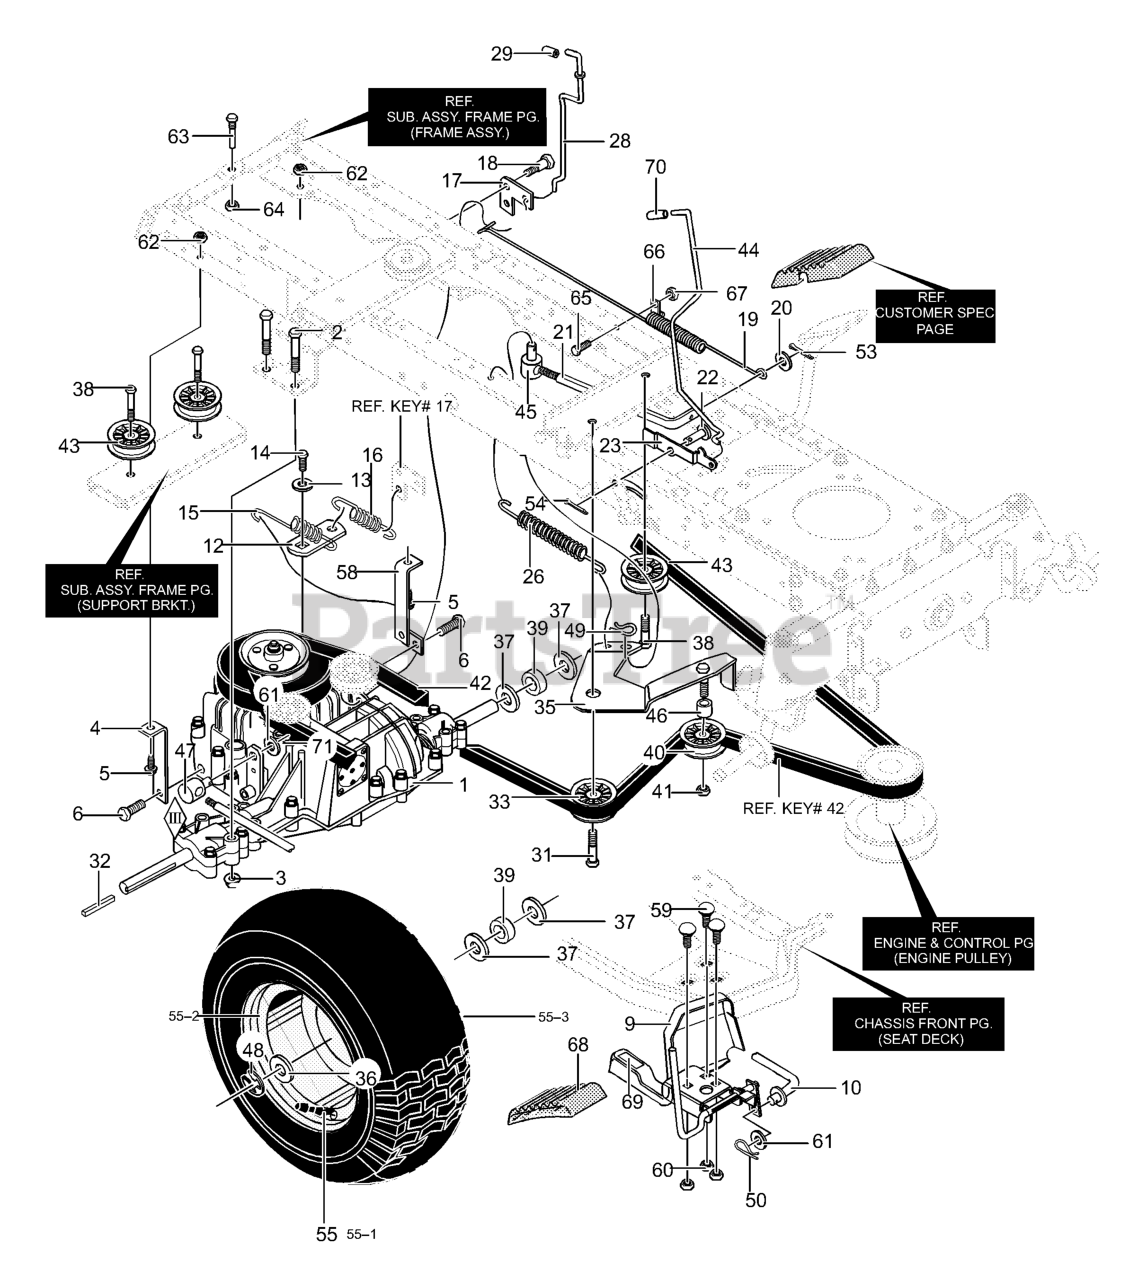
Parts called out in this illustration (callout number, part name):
1	Transaxle, VST205 **
2	Screw, 5/16-18 x 2.50
3	Nut, 5/16-18
4	Bracket, Stabilizer Hydro
5	Screw, 5/16-18 x 1.00
6	Screw, 5/16-18 x 0.75
9	Pedal Assy. Hydro
10	Rod, Foot Control
12	Bracket, Shift
13	Washer, Transaxle
14	Screw, 1/4-28x.750
15	Spring - Transaxle Disconnect
17	Bracket, Disconnect Lever
18	Bolt, HHSH 5/16-18
19	Spring, Brake
20	Washer, Flat
21	Rod, Clutch
22	Pin, Clevis
23	Latch, Park Brake
26	Spring, Tension
28	Rod, Disconnect
29	Grip, Hydro Disconnect
31	Screw, 3/8-16 x 1.25
32	Key, Square
33	Pulley, Idler
35	Assy, Idler Arm Traction
36	Washer, Flat
37	Washer, Flat
38	Screw, 3/8-16 x 1.25
40	Pulley, Idler
41	Nut, 3/8-16
42	Belt, V 4L 112.75
43	Pulley, Idler
44	Park Brake Rod
45	Nut, 5/16-18 Adjusting
47	Adjust Nut 1/2-13
48	E-Ring
49	Pin, Hair
50	Pin, Hair
53	Pin, Cotter
54	Pin, Cotter
55	Tire & Rim
55-1	Valve Stem
58	Bracket, Stabilizer Assy.
59	Bolt, 5/16-18x.75 Carr.
60	Nut, 5/16-18 Hexwdfllk Whiz
61	Flatwasher
62	Nut, 1/4-20
63	Screw Guide
64	Nut, 5/16-18 Hexwdfllk
65	Screw, 1/4-20x.50
66	Retainer, Wire
67	Nut, 1/4-20 Wdflwhiz-lk
68	Pad, Speed Control Pedal
69	Pad, Toe Sandpaper
70	Cap, Dump Valve Rod
71	Hair Pin
